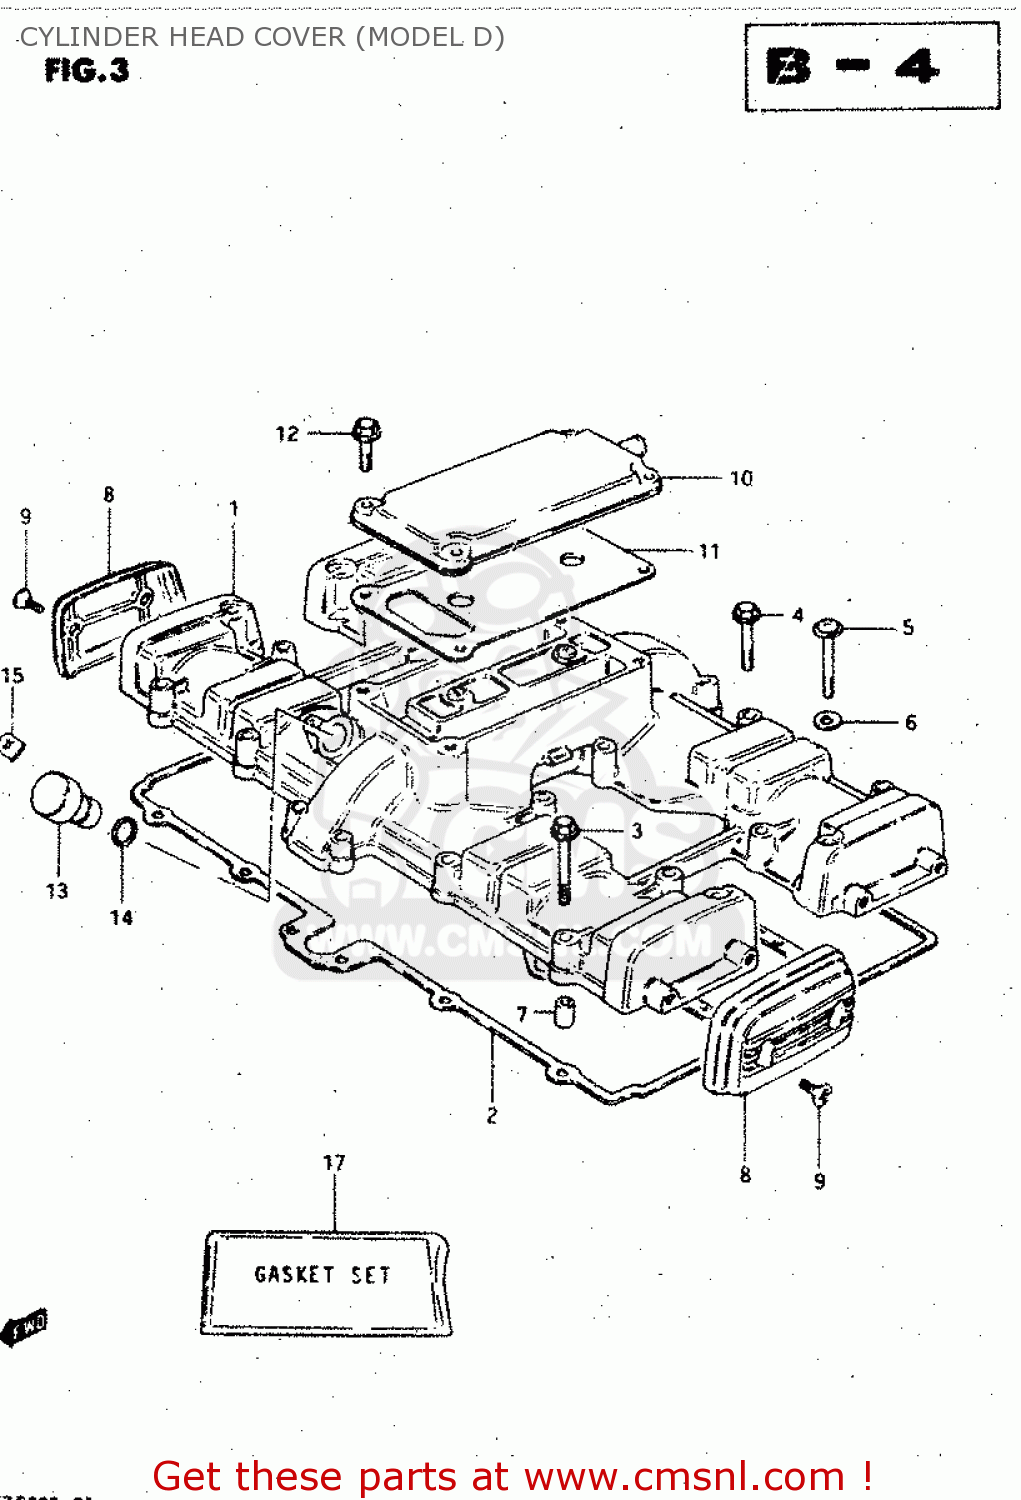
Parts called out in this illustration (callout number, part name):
1	COVER,CYLINDER HEAD
2	GASKET,CYLINDER HEAD COVER (MCA)
3	BOLT (6X40)
4	BOLT
5	SCREW 6X40
6	WASHER
7	PIN(6.2X8X11)
8	CAP,CYLINDER HEAD COVER
9	SCREW(5X12)
10	COVER,BREATHER
11	GASKET (MCA)
12	BOLT
13	PLUG,TACH GEAR SLEEVE HOLE
14	SEAL,TACHOMETER DRIVEN
15	PLATE,TACH DRIVE GEAR SLEEVE
16	SCREW(5X12)
17	GASKET SET (MCA)
